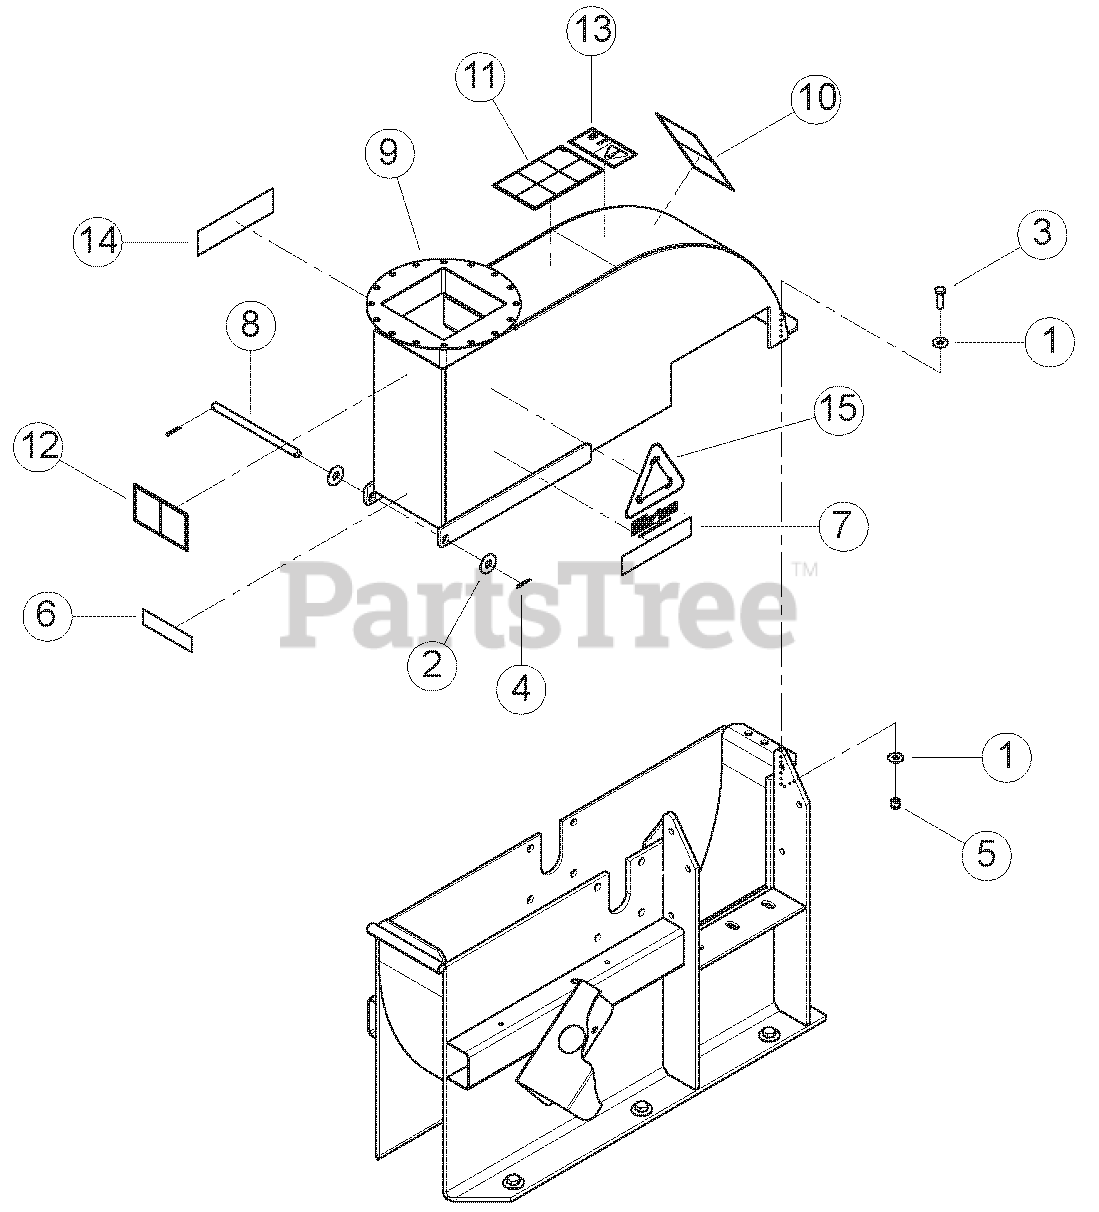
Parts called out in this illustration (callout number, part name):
1	WASHER, 3/8 FLAT ZP
2	WASHER, 1/2 FLAT ZP
3	BOLT, 3/8 X 1-1/4 HEX HD GR5 ZP
4	PIN, 1/8 X 1 COTTER
5	NUT, 3/8 NE NYLOCK ZP
6	DECAL, ATLANTIC BRIDGE LTD INFO (CE COMPLIANT MODELS)
7	DECAL, MODEL CH911DH
7	DECAL, MODEL CH922DH
8	SHAFT, CHIPPER TOP PIVOT
9	ASSEMBLY, CHIPPER TOP HOUSING, SERVICE PART
10	DECAL, KNIFE ACCESS ISO
11	DECAL, OPERATING INSTRUCTIONS ISO
12	DECAL, DISCHARGE ISO
13	DECAL, MAINTENANCE ISO
14	DECAL, ECHO BEARCAT 6.82 X 1.90
15	DECAL, CHIP IT
